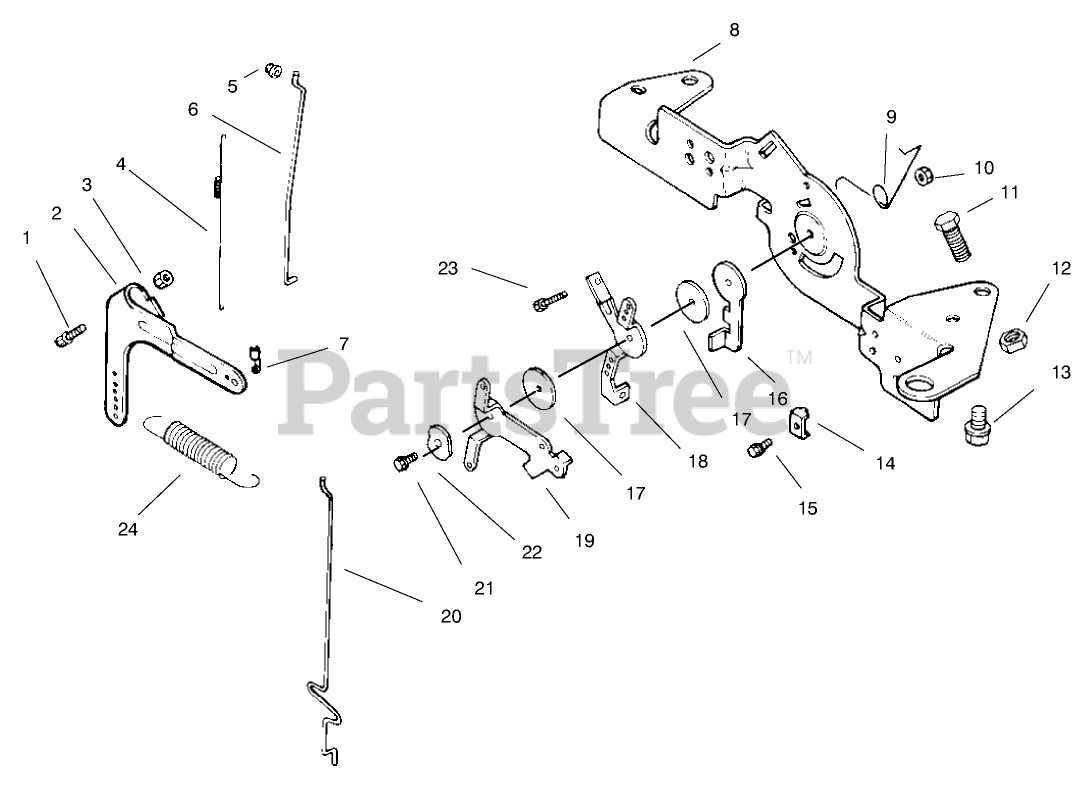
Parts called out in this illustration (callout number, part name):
1	Screw
2	Lever-Govenor
3	Nut
4	Spring-Linkage
5	Bushing-Linkage
6	Linkage-Throttle
7	Bushing-Linkage
8	Bracket-Control
9	Spring-Choke Return
10	Nut
11	Screw-HF
12	Nut
13	Screw
14	Clamp
15	Screw-HF
16	Lever-Actuator, Throttle
17	Washer
18	Lever-Throttle Control
19	Lever-Choke
20	Linkage-Choke
22	Washer-Wave
23	Screw-Hex.
24	Carriage Bolt
